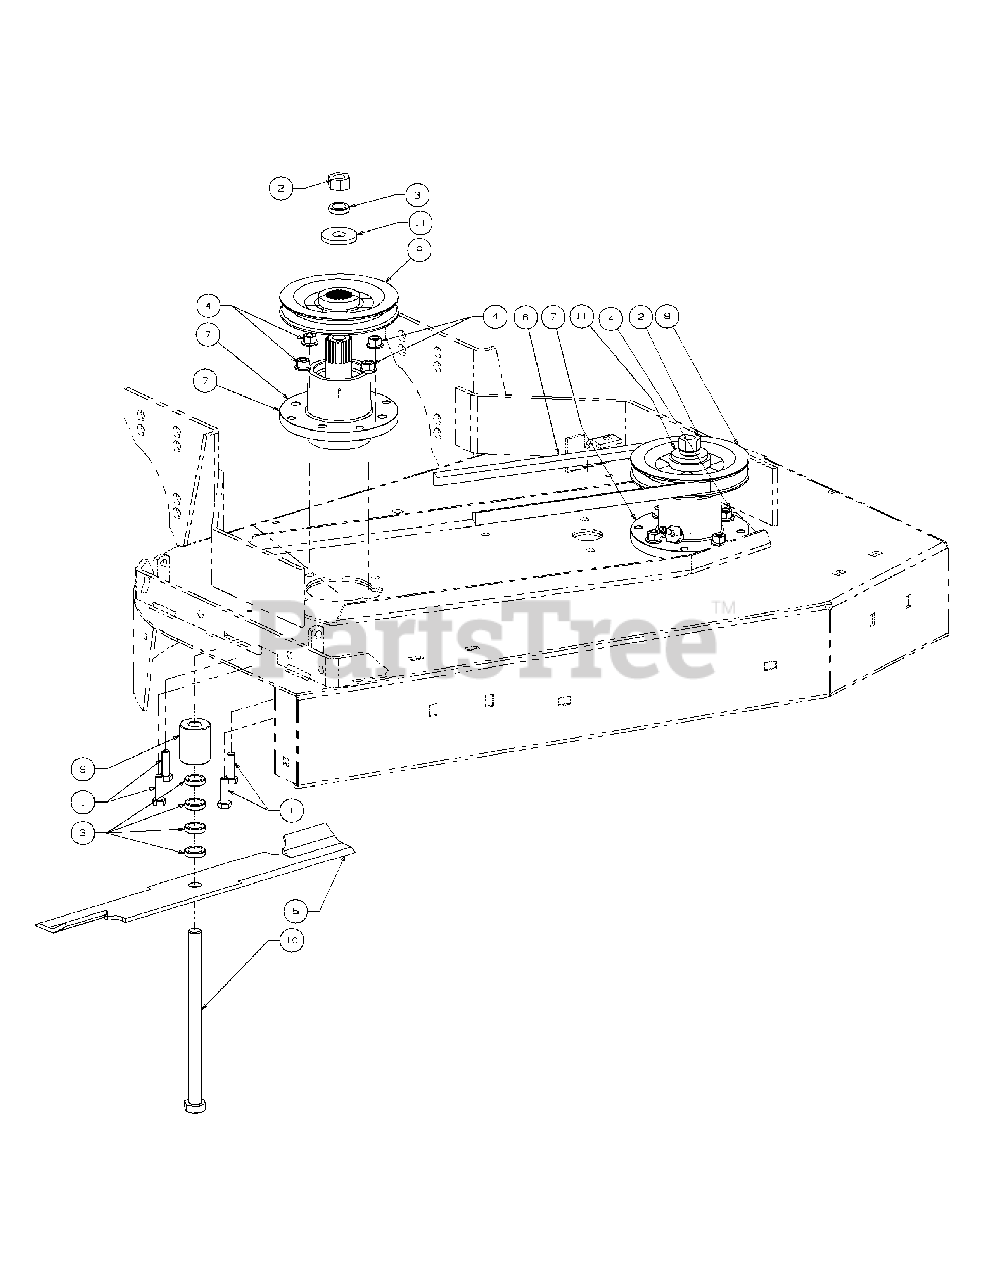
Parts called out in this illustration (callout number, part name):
1	Hex Cap Screw, 3/8-16 x 1-1/2
2	Hex Nut, 5/8-11
3	Blade Spacer, 5/8 ID, 1/4 Thick
4	Hex Nut Flange Lock, 3/8-16
5	18" Rotary Blade
7	Spindle Assembly
7	Grease Fitting, 1/4-28 x 1.609
8	Deck Pulley
9	Blade Spacer, .630 x 1.500 x 1.850
10	Hex Cap Screw, 5/8-11 x 9
11	Flat Washer, .656 ID x 1.313 OD
